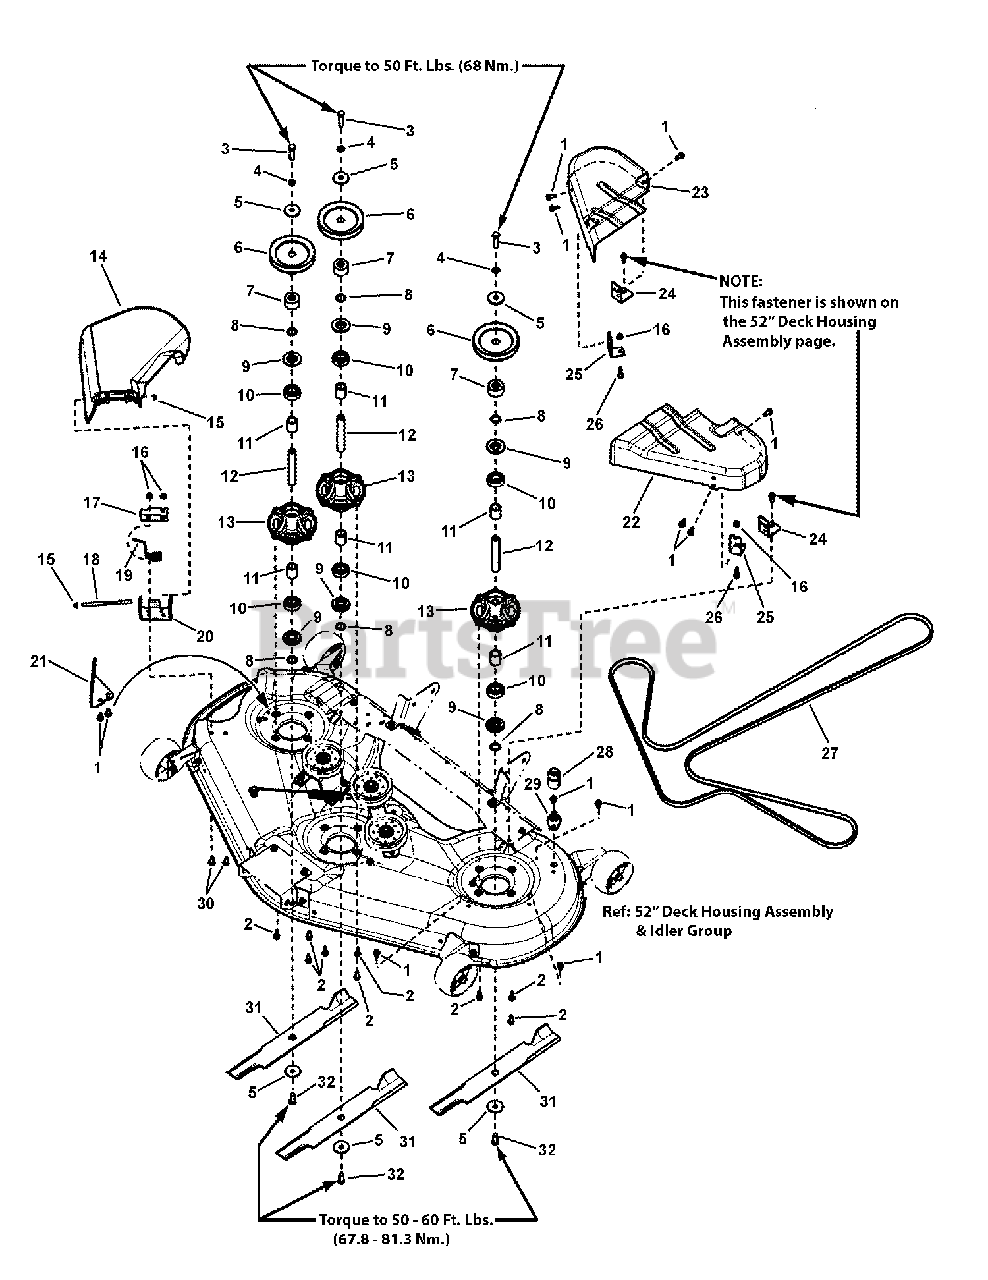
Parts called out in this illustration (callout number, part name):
1	SCREW, 5/16-18 x 3/4" Hex Washer Head Self-Tap, Black
2	SCREW, 5/16-18 x 1" Hex Washer Head Self-Tap, Black
3	SCREW, 7/16-14 x 1-3/4" Hex Head Cap, GR 5, Black
4	LOCKWASHER, .438, Spring, Black
5	WASHER, .475 ID x 1.75 OD x .156 Thick Spring, Black
6	PULLEY, 5.5 OD 11 Ga. Split 52" Mower
7	SPACER, Pulley, Powdered Metal
8	RING, Self Locking
9	SHIELD, Arbor, 2.050 OD
10	BALL BEARING, 20 MM
11	SPACER, Bearing Powdered Metal
12	SHAFT, Spindle 20MM Dia. 134.60 MM Long
13	HOUSING, Spindle, Cast Aluminum (Machined) w/Grease Fitting
14	DEFLECTOR, Discharge, Plastic 46/52 Decks
15	PUSH NUT, 5/16"
16	NUT, 5/16-18 Hex Flange Lock, Small - Black
17	PLATE, Deflector, Closeoff
18	ROD, Hinge, .313 Dia. x 5.6 Long, Zinc Plated
19	SPRING, Torsion, Deflector, 2.16 Long
20	HINGE, Deflector, 52"
21	BAFFLE, Pinchoff
22	COVER, Spindle, 46/52 Deck, LH 285Z
23	COVER, Spindle, 46/52 Deck, RH 285Z
24	BRACKET, Rear Deck Cover Support 285Z
25	BRACKET, 46"/52" Cover Mounting
26	SCREW, 5/16-18 x 1-1/4" Hex Washer Face Self-Tap
27	BELT, RZT, 52" Deck, HA Section, 158" Effective Length
28	CONNECTOR, Washout Port 46/52" Black Poly
29	ADAPTER, Washout Port 46/52" Mowers
30	BOLT, 5/16-18 x 7/8" Round Head Short Square Neck, GR 5, Black
31	BLADE, Mower, 18.50 Long, 52" Deck
32	SCREW, 7/16-14 x 1" Hex Head Cap, GR 5, Black
